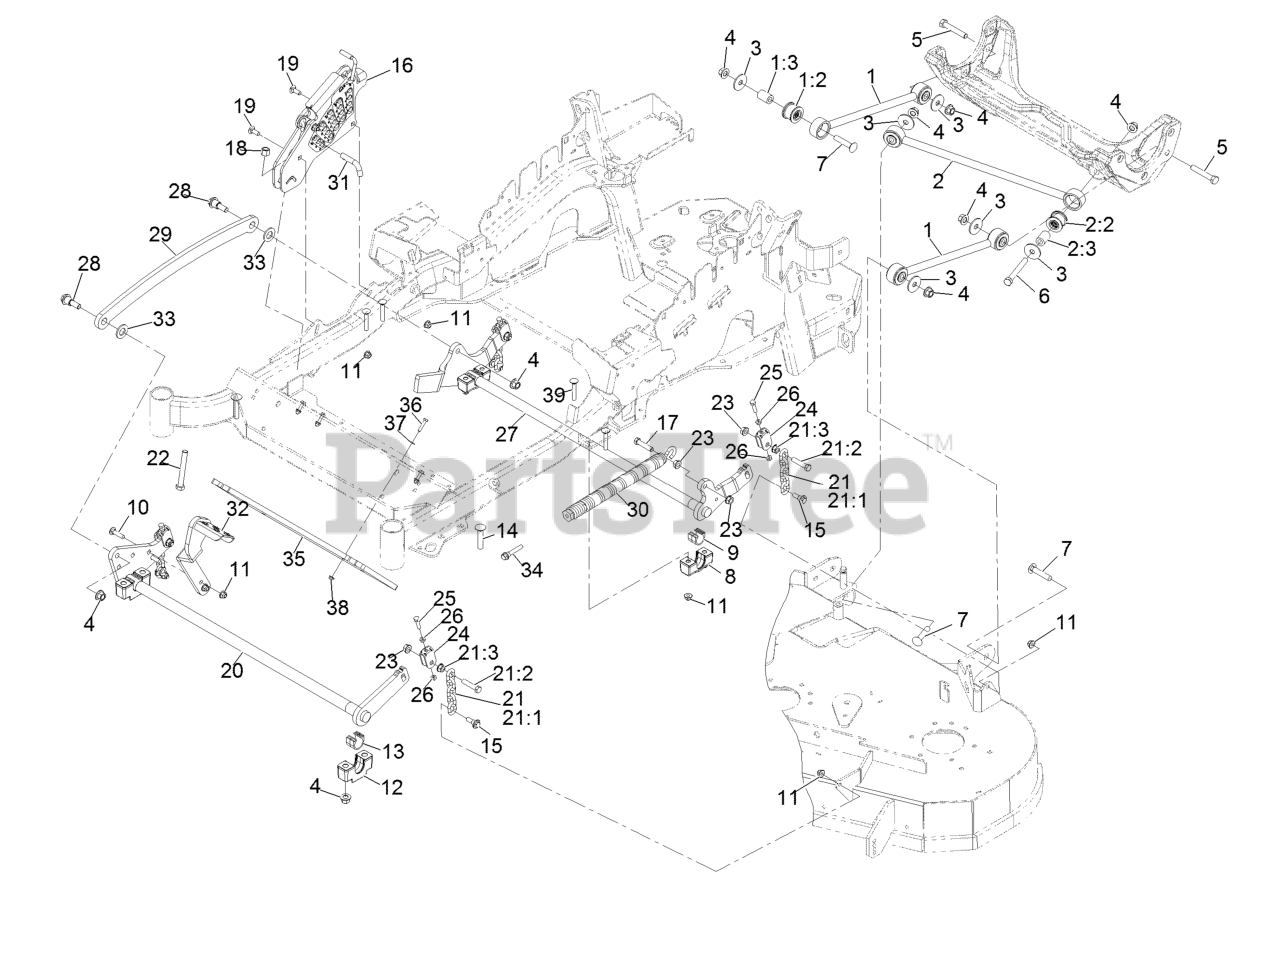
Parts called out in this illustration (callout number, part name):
1	Deck Strut ASM
1:2	Bushing-Suspension, Rubber
2	Panhard Rod ASM
2:2	Bushing-Suspension, Rubber
4	Nut-Lock 1/2-13
5	Screw-HH 1/2-13 X 3
6	Screw-HH 1/2-13 X 4
7	Bolt-Carriage 1/2-13 X 2 1/2
8	Support-Cross Shaft, Bearing Rear
9	Bearing-Cross Shaft, Rear
10	Bolt-Carriage 3/8-16 X 1 1/2
11	Nut-Nyloc 3/8-16 Flg
12	Support-Cross Shaft, Bearing
13	Bearing-Cross Shaft, Front
14	Bolt-Carriage 1/2-13 X 2 1/2 Spl Neck
15	Screw-Hex Flange 3/8-16 X .80
16	HOC ASM
17	Screw-HH 7/16-14 X 2
18	Nut-Nyloc 1/2-13
19	Bolt-Carriage 3/8-16 X 1
20	Decklift-Front
21	Deck Lift Chain ASM
21:1	Chain-Lift, Deck
21:2	Screw-HH 7/16-14 X 2
21:3	Nut-Whizlock 7/16-14
22	Bolt-HH 1/2-13 X 4 Tap
23	Nut-Whizlock 7/16-14
24	Yoke-Adjust, Deck
25	Screw-HH 5/16-18 X 1 1/4
26	Nut-Jam 5/16-18
27	Lift-Deck, Rear
28	Screw-Shoulder HHF 1/2-13 X 1.12
29	Link-Lift, Deck
30	Spring-Extension
31	Pin-HOC
32	Lever-Foot
33	Washer-3/4 SAE
34	Screw-Shcs 3/8-16 X 2.212
35	Weight-Toe Board
36	Screw-HH 1/4-20 X 1 1/4
37	Washer-1/4 SAE
38	Nut-Nyloc 1/4-20 Flg
39	Bolt-Carriage 3/8-16 X 2 1/4
